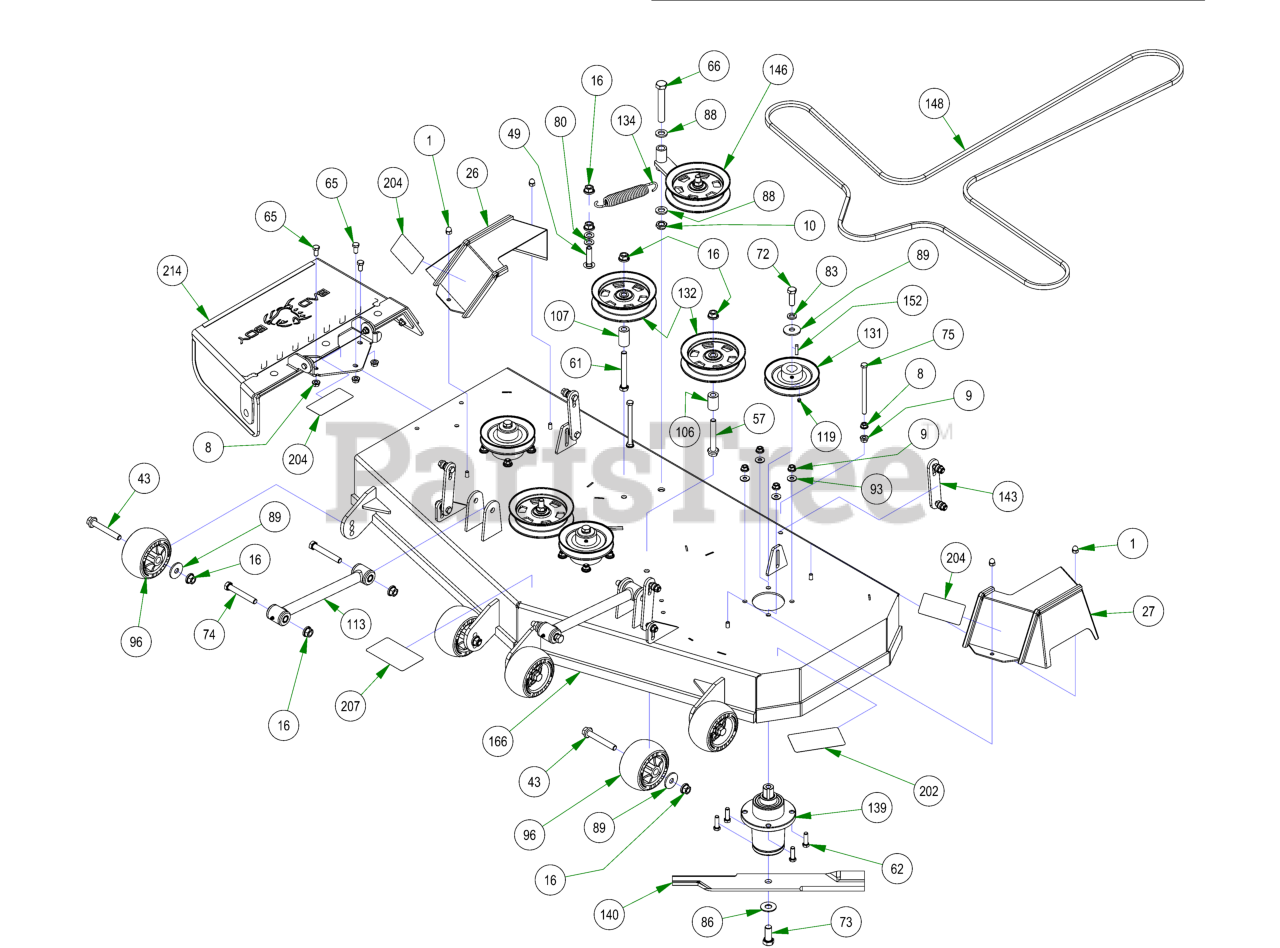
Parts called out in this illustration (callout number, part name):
1	5/16-18 ACORN NUT HIGH-CROWN ZC
8	3/8-16 HEX SERRATED FLANGE NUT HARD/ZINC
9	3/8-16 NYLON INSERT FLANGE LOCKNUT (GR.F) ZINC
10	5/8-11 NYLON INSERT JAM LOCKNUT ZINC
16	1/2-13 NYLON INSERT FLANGE LOCKNUT ZINC
26	2021 Maverick 54”/60” RH Pulley Cover
27	2021 Maverick 54”/60” LH Pulley Cover
43	1/2-13 X 90MM HEX FLANGE BOLT W/SHOULDER (GR.8) ZINC
49	1/2-13 X 2 CARRIAGE BOLT ZINC
57	1/2-13 X 3-1/2 HEX FLANGE BOLT (GR.8) ZINC
61	1/2-13 X 4 HEX CAP SCREW (GR.8) ZINC YELLOW
62	3/8-16 X 1-1/4 HEX CAP SCREW (GR.5) ZINC
65	3/8-16 X 3/4 HEX CAP SCREW (GR.5) ZINC
66	5/8-11 X 4 HEX CAP SCREW (GR.8) ZINC YELLOW
72	1/2-20 X 1-1/2 HEX CAP SCREW (GR.5) ZINC
73	5/8-18 X 1-1/2 HEX CAP SCREW (GR.8) ZINC YELLOW
74	1/2-13 X 3-1/2 HEX CAP SCREW (GR.5) ZINC
75	3/8-16 X 5-1/2 HEX CAP SCREW (GR.5) ZINC
80	.517 SQ WDTH ID X .937 OD X .060 THICK F/W PHOS/OIL
83	1/2 SPLIT LOCKWASHER (GR.8) ZINC/YELLOW
86	5/8 USS FLAT WASHER (1-3/4" OD) GR.8 ZINC YELLOW
88	.635 ID X 1.120 OD X .140 THICK FLAT WASHER NYLON
89	1/2 BELLEVILLE WASHER (1-5/8 OD X .140 THK) ZINC
93	5/16 USS FLAT WASHER (7/8 OD) ZINC
96	Deck Wheel
106	.502 ID X .750 OD X 1.500 Long Spacer
107	1 3/4" Pulley Spacer
113	Hybrid Turnbuckle/Deck Locator
119	5/16-24 X 1/4 SOCKET SET SCREW (CUP PT) PLAIN
131	5.25" Deck Spindle Pulley
132	5-3/4 Idler Pulley
134	Deck Idler Spring
139	Spindle Assembly
140	54" Fusion Blade for ZT/Mav/Outlaw/Revolt
143	Deck Hanger Assembly
146	2017 54"/48" Deck Idler Assembly
148	B155.75 Deck Belt
152	1/4 X 1 SQ MACHINERY KEY 1018 STL PLN
166	54 ZT Welded Deck
202	2018 54" Deck Decal
204	Danger Decal-Spindle/Discharge
207	Deck Belt Route Decal
214	Discharge Chute Assembly
